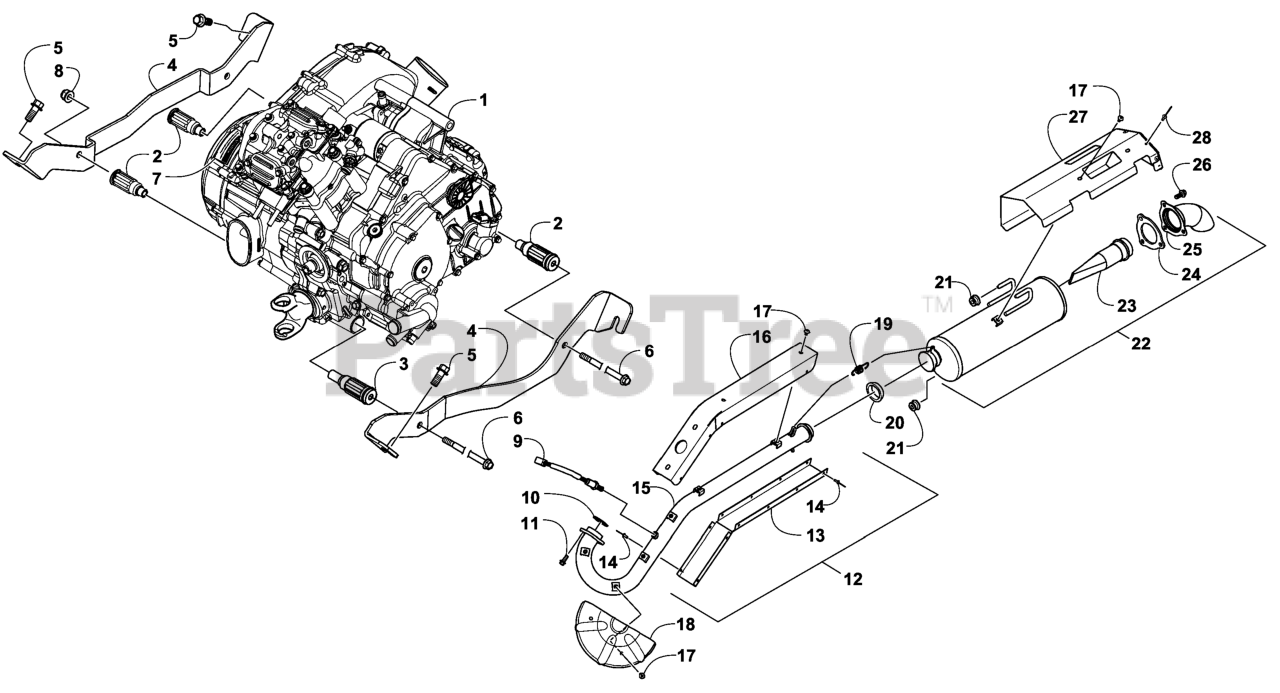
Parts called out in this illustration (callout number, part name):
1	ENGINE-HDX 450 W/RUBBER M
3	BUSHING-RUBBER, LONG
4	BRACKET-ENGINE, RH
4	BRACKET-ENGINE, LH
6	SCREW-HFH
7	DECAL-WARNING, CLUTCH COV
9	GUIDE-BELT
10	SEAL-EXHAUST PIPE
11	SCREW-HFH
12	PIPE-EXHAUST
13	SHIELD-PIPE, LOWER
15	PIPE-EXHAUST, HI TEMP
16	SHIELD-PIPE, UPPER-REAR
17	SPROCKET,GEARBOX 5 SPEED
19	SPRING-EXTENSION
20	SEAL-EXHAUST
21	GROMMET-EXHAUST HANGER
22	MUFFLER ASM
23	SPARK ARRESTER
24	GASKET-SPARK ARRESTER
25	TAIL PIPE ASM
26	SCREW-HFH
27	SHIELD-MUFFLER
28	BELT,COG
